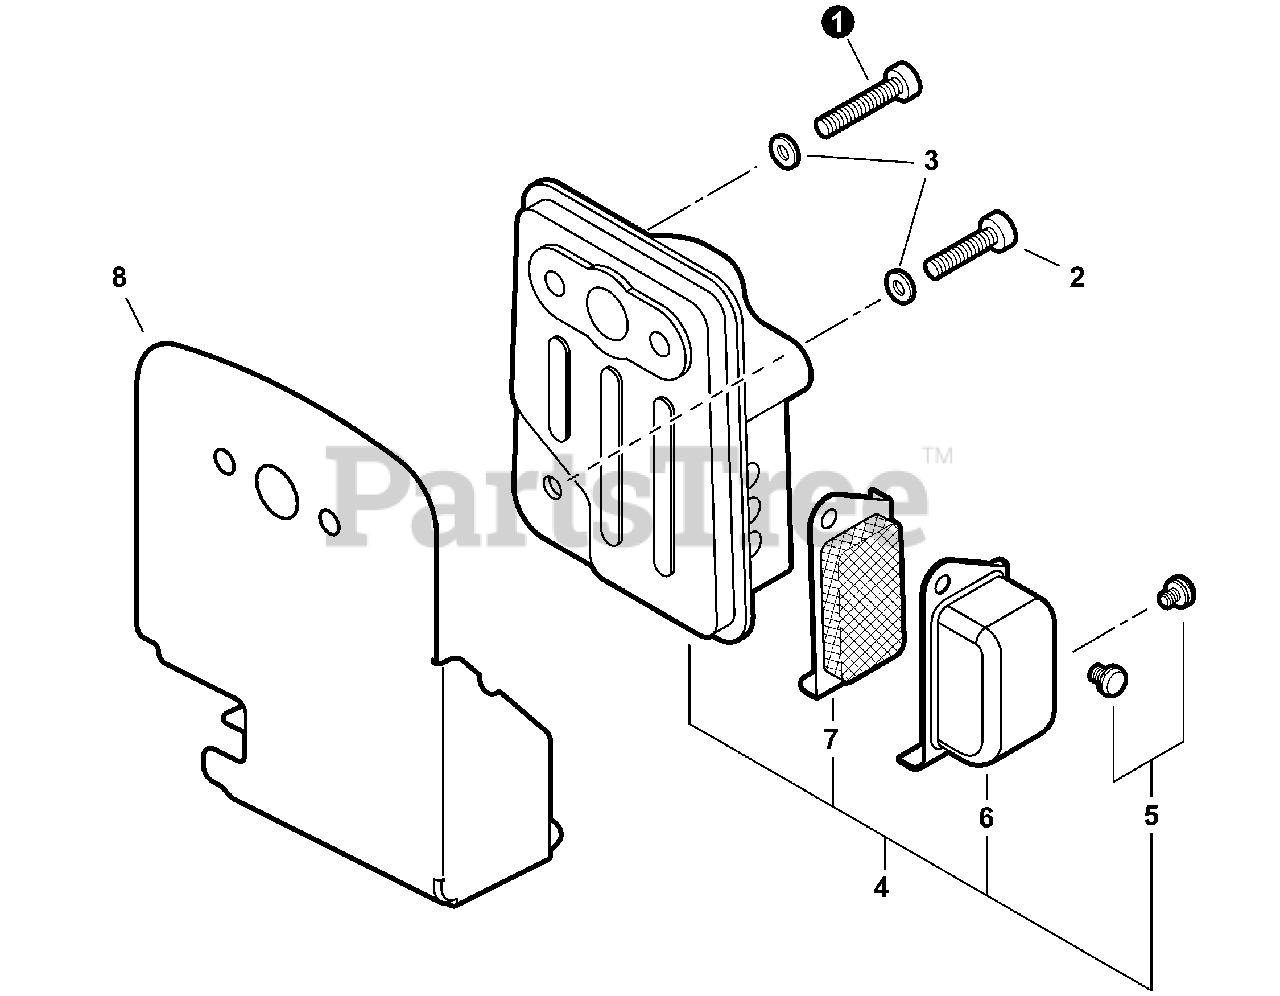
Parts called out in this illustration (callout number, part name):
1	BOLT M5×25
2	BOLT 5×16
3	WASHER, FLAT 5.5×10×0.8
4	MUFFLER ASSY
5	SCREW M4×6
6	GUIDE, EXHAUST
7	SCREEN, SPARK ARRESTER
8	HEAT SHIELD, EXHAUST
